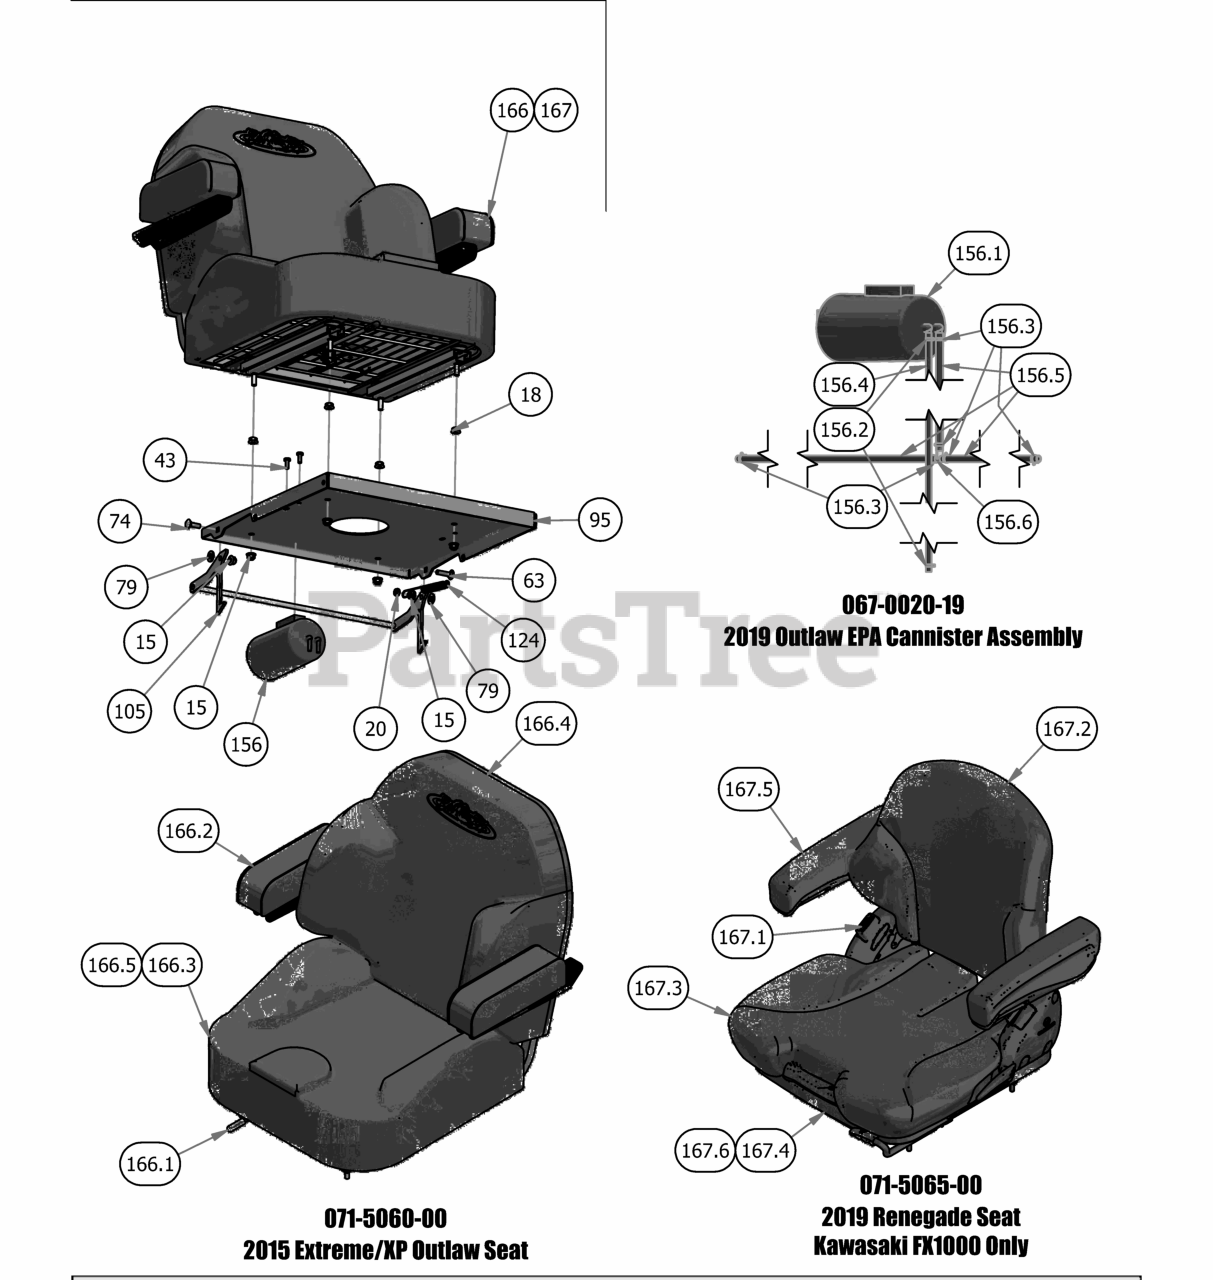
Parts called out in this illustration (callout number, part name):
156.1	Carbon Canister
156.2	3/16" Vinyl Hose Clamp
156.3	3/16 Vinyl Clamp
156.4	3/16" Vinyl Tubing, 66" Long
156.5	1/4" Vinyl Tubing 38" Long
156.6	fuel line T
166.1	Extreme/XP Outlaw Seat Rails (Pair)
166.2	Extreme/XP Outlaw Seat Arm Rest (Pair)
166.3	Extreme/XP Outlaw Seat Cushion-Bottom
166.4	Extreme/XP Outlaw Seat Cushion-Back
166.5	Seat Switch
167.2	Backrest Cushion
167.3	Seat Cushion
167.4	Slave & Adjuster
167.5	Arm Rest Kit
167.6	Seat Switch
